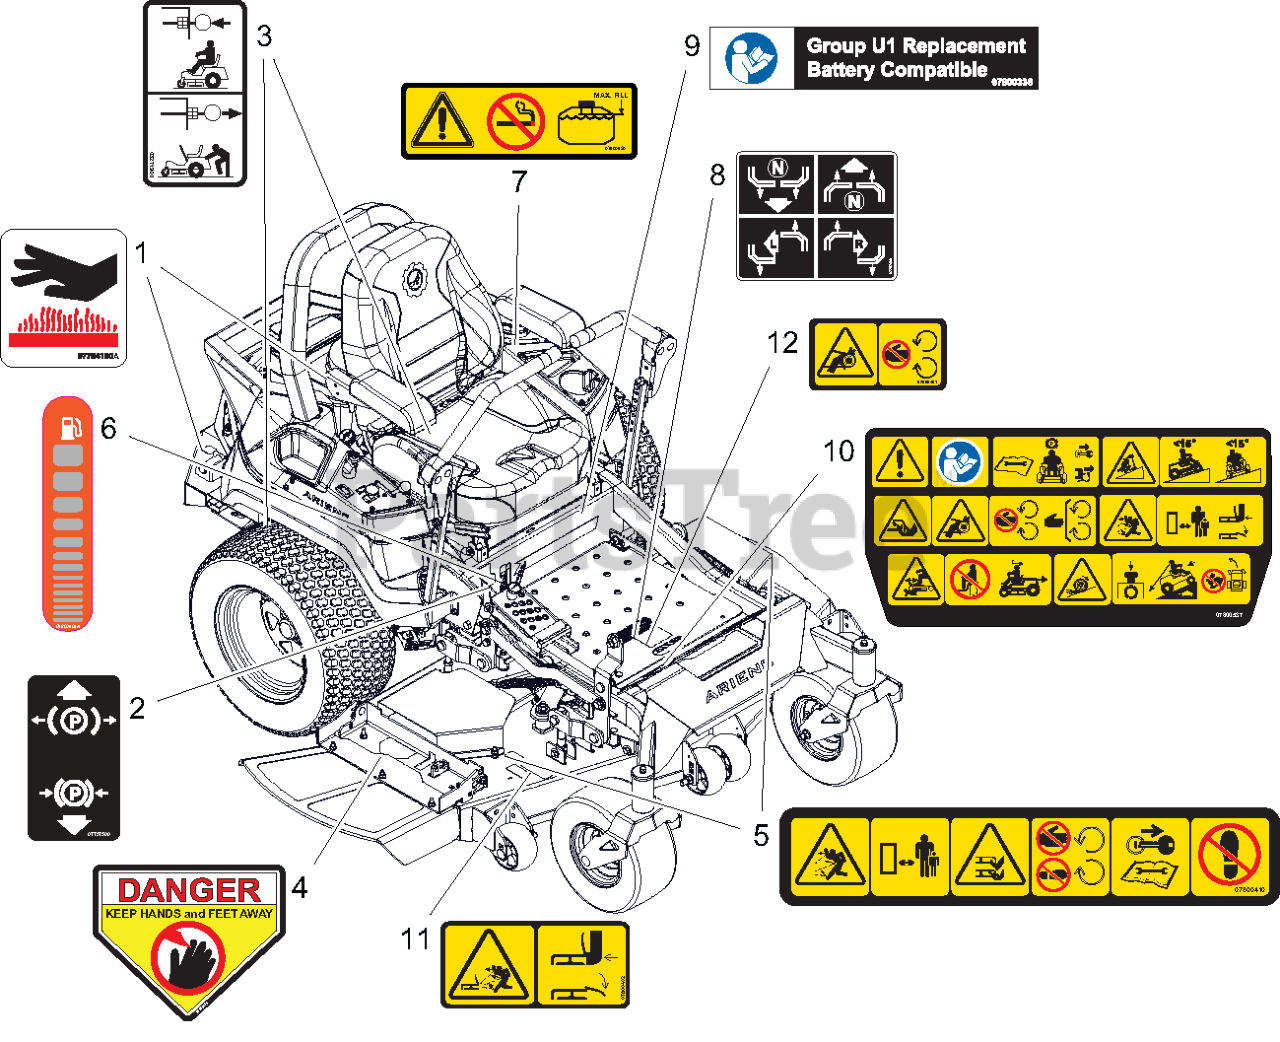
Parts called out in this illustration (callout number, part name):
1	DECAL, HOT SURFACE
2	DECAL, PARKING BRAKE LEVER
3	DECAL, TRANSMISSION DISCONNECT
4	DECAL, DANGER
5	DECAL, DECK SAFETY
6	DECAL, ARIENS FUEL LEVEL
7	DECAL, FUEL WARNING
8	DECAL, INSTRUCTIONAL-STEERING
9	DECAL, U1 BATTERY REPLACEMENT
10	DECAL, MAIN SAFETY
11	DECAL, SAFETY - DECK GUARDING
12	DECAL, SAFETY - GUARDING
